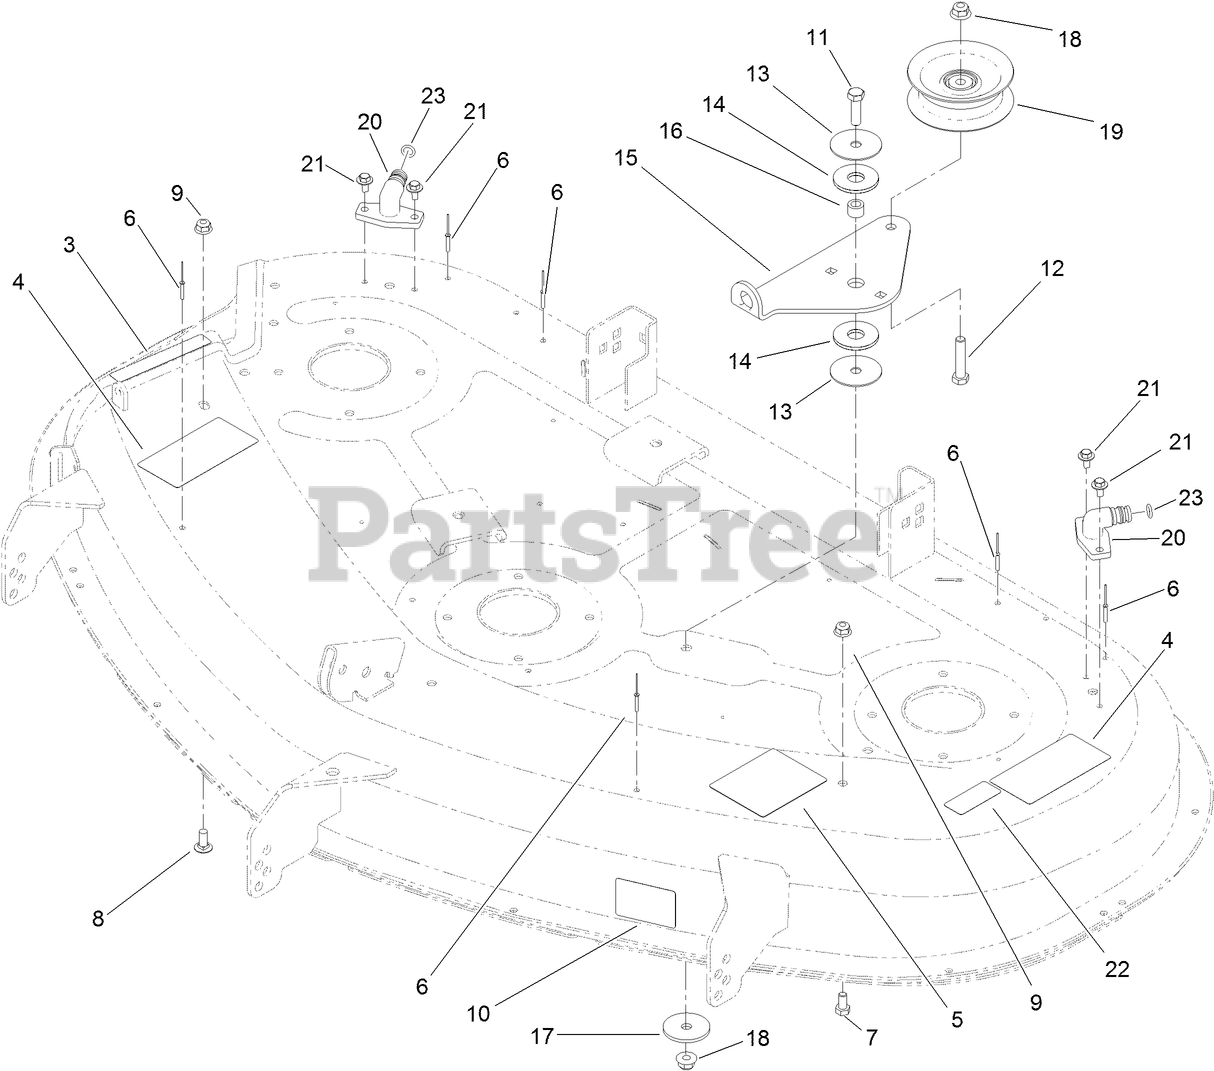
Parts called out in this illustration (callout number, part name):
3	DECAL-DANGER
4	DECAL-DANGER, DECK
5	DECAL-ROUTING, BELT
6	RIVET-BLIND
7	SCREW-HH
8	SCREW-CARR
9	NUT-HF, NI
10	DECAL-SCALP, ANTI
11	SCREW-HH
12	SCREW-HH
13	WASHER
14	WASHER-FRICTION, COMPOSITE
15	ARM-IDLER
16	SPACER
17	WASHER-REBOUND
18	NUT-HF, NI
19	PULLEY-IDLER, FLAT
20	FITTING-WASHOUT
21	SCREW-HHFTF
22	SERVICE DECAL
23	O-RING
